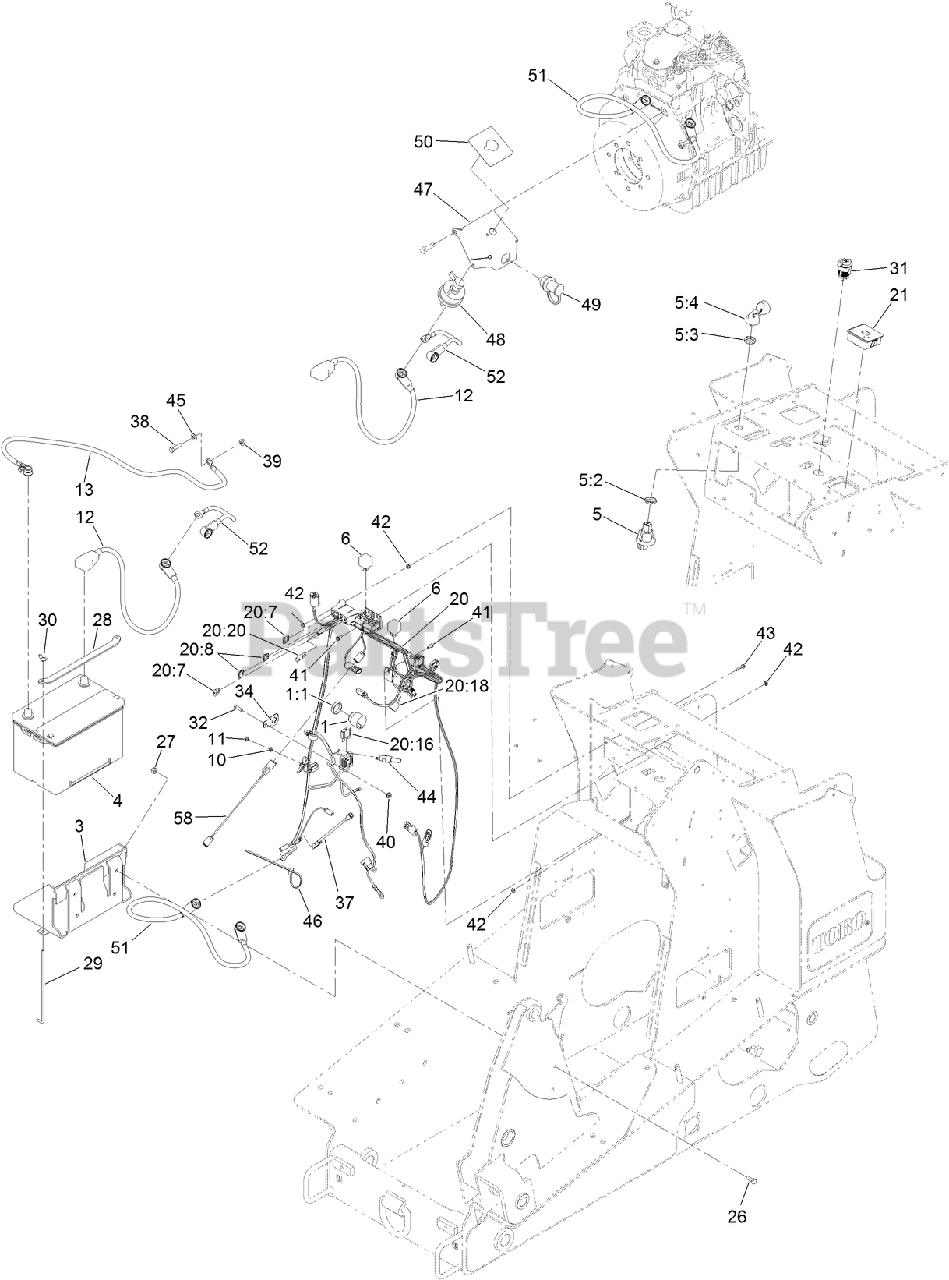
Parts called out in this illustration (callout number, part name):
1	AUDIO ALARM ASM
1:1	NUT-PLASTIC, KNURLED
3	TRAY-BATTERY
4	BATTERY
5	IGNITION SWITCH ASM
5:2	NUT-HEX
5:3	NUT-FACE
5:4	IGNITION KEY SET
10	WASHER-LOCK, SPRING
11	NUT-HEX
12	CABLE-BATTERY, POSITIVE
13	CABLE-NEGATIVE
20	HARNESS-WIRE
20:7	FUSE-BLADE, 10 AMP
20:8	FUSE-BLADE, 15 AMP
20:16	FUSE-BLADE, 50 AMP
20:20	CAP-PLUG
21	MODULE-HOUR METER
26	SCREW-HH
27	NUT-LOCK, NI
28	STRAP-HOLD DOWN, BATTERY
29	ROD-HOLD DOWN, BATTERY
30	Wingnut
31	RECEPTACLE-12V
32	SCREW-HH
34	CLIP-FUSE
37	HARNESS-LINK, FUSIBLE
38	SCREW-HH
39	NUT-HF, NI
40	NUT-HF
41	SCREW-HWH
42	NUT-KEPS
43	SCREW-HWHTF
44	SWITCH-TEMP
45	WASHER-PLAIN
46	TIE-CABLE
47	MOUNT-REMOTE TERMINAL
48	SWITCH-DISCONNECT, MASTER
49	STUD-JUMPER, POSITIVE
50	DECAL-BATTERY DISCONNECT
51	CABLE-BATTERY, POSITIVE
52	CABLE-BATTERY, POSITIVE
58	HARNESS-WIRE
